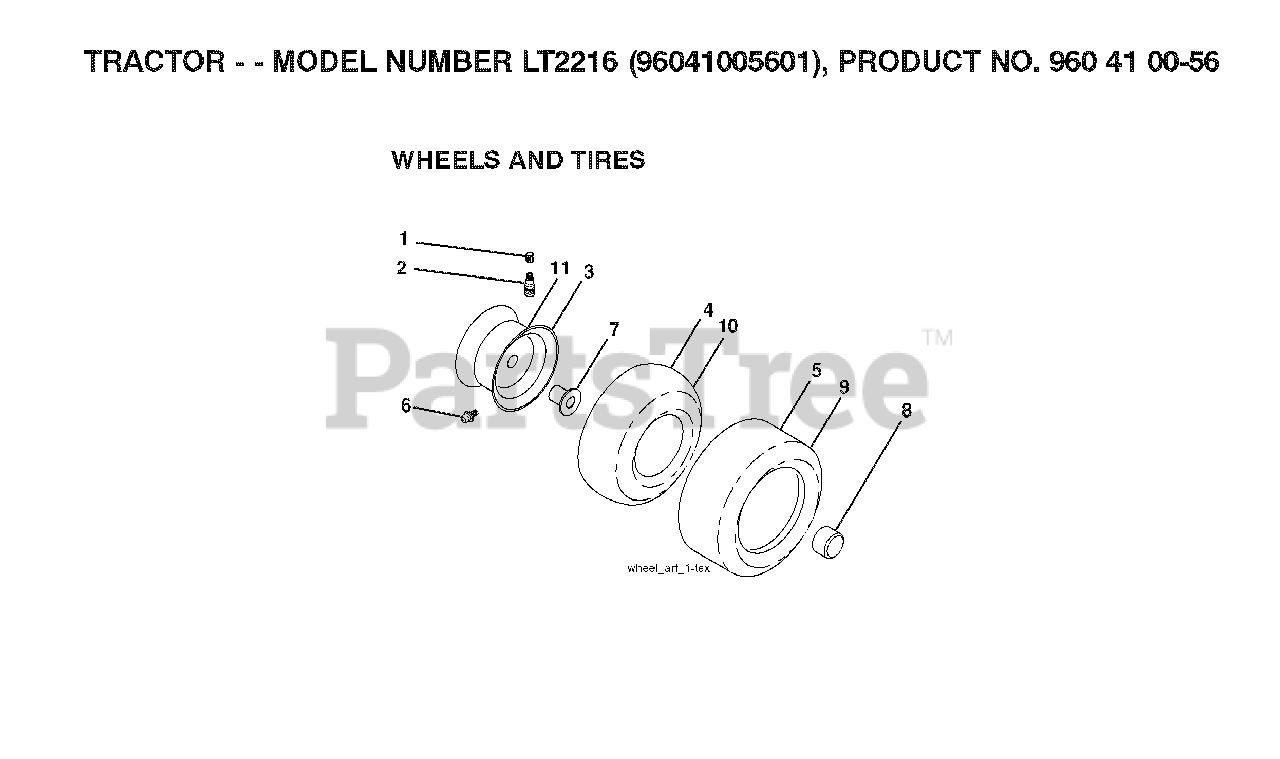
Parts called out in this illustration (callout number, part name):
1	VALVE CAP
2	VALVE STEM LT
3	RIM ASM 6" FRONT SILVER
4	TUBE.5.3/4.5/6
5	TIRE HEAVY DUTY
6	FITTING LT
7	BEARING T
8	CAP, AXLE BLK
9	TIRE HEAVY DUTY
10	TUBE
11	RIM ASM 8" REAR SILVER
